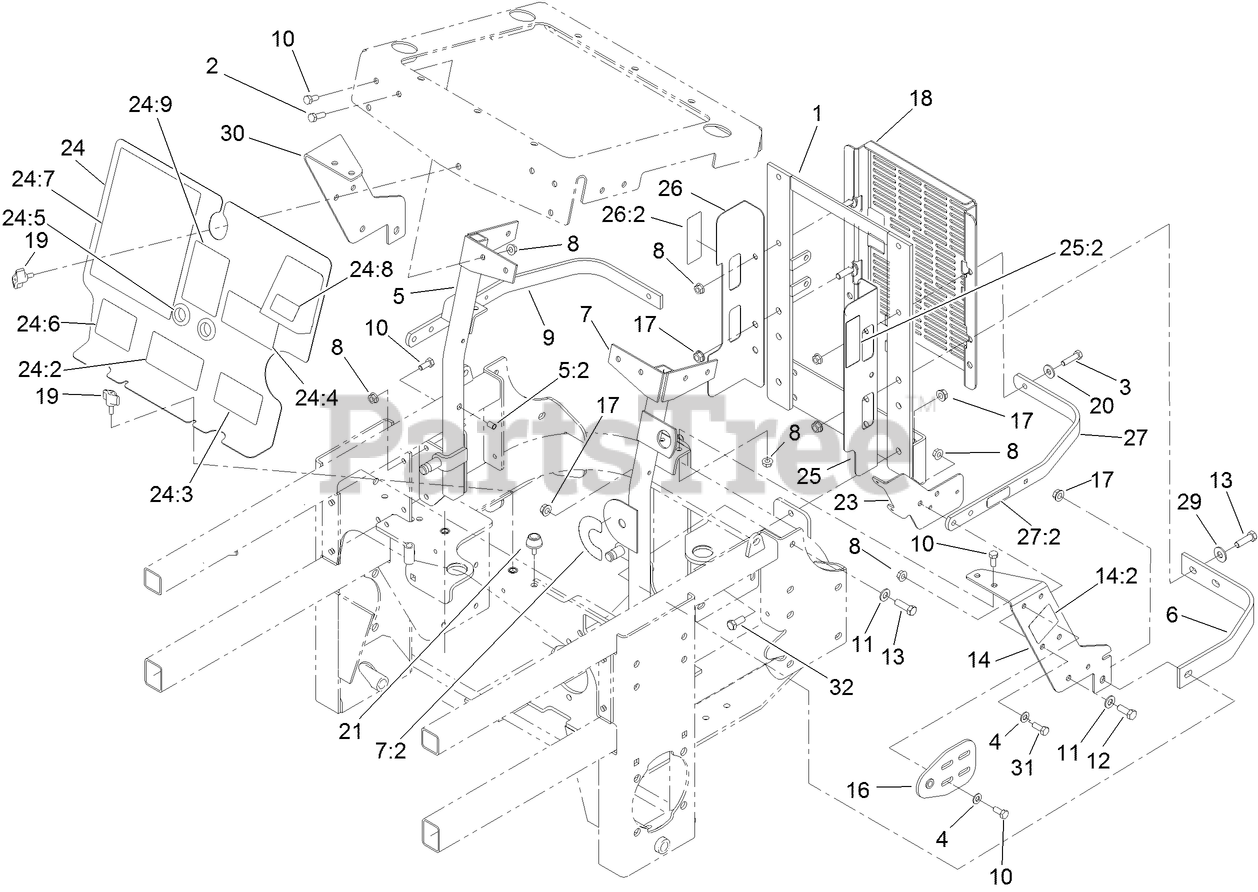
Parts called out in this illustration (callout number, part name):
1	SUPPORT-RADIATOR, REAR
2	SCREW-HH
3	SCREW-HH
4	WASHER-PLAIN
5	RH RADIATOR BRACE ASM
5:2	NUT-CLINCH
6	STRAP-GUARD
7	LH RADIATOR BRACE ASM
7:2	DECAL-VALVE, FUEL
8	NUT-HF
10	SCREW-HH
11	WASHER-FLAT
12	SCREW-HH
13	SCREW-HH
14	LH SUPPORT BRACKET ASM
14:2	DECAL-FUSE
16	PLATE-PIVOT, HOOD
17	NUT-HHF, WHIZ
18	SHIELD-COOLER
20	WASHER-FLAT
21	BUMPER-RUBBER
23	BRACKET-RELAY, FUSE
24	FRONT ENGINE SHIELD ASM
24:2	DECAL-DANGER, ROTATING DEVICES
24:3	DECAL-ROUTING, HYDRO BELT
24:4	DECAL- WARNING, BUZZER
24:5	GROMMET-RUBBER
24:6	DECAL-ROUTING, CLUTCH BELT
24:7	DECAL-CHECK, SERVICE
24:8	DECAL-CAUTION
24:9	DECAL-COOLANT
25	LH FAN GUARD ASM
25:2	DECAL-FAN, RADIATOR
26	RH FAN GUARD ASM
26:2	DECAL-FAN, RADIATOR
27	TOP STRAP ASM
27:2	DECAL-RELAY
29	WASHER-FLAT
30	BRACKET-SUPPORT, RH
31	SCREW-HH
32	SCREW-HH
